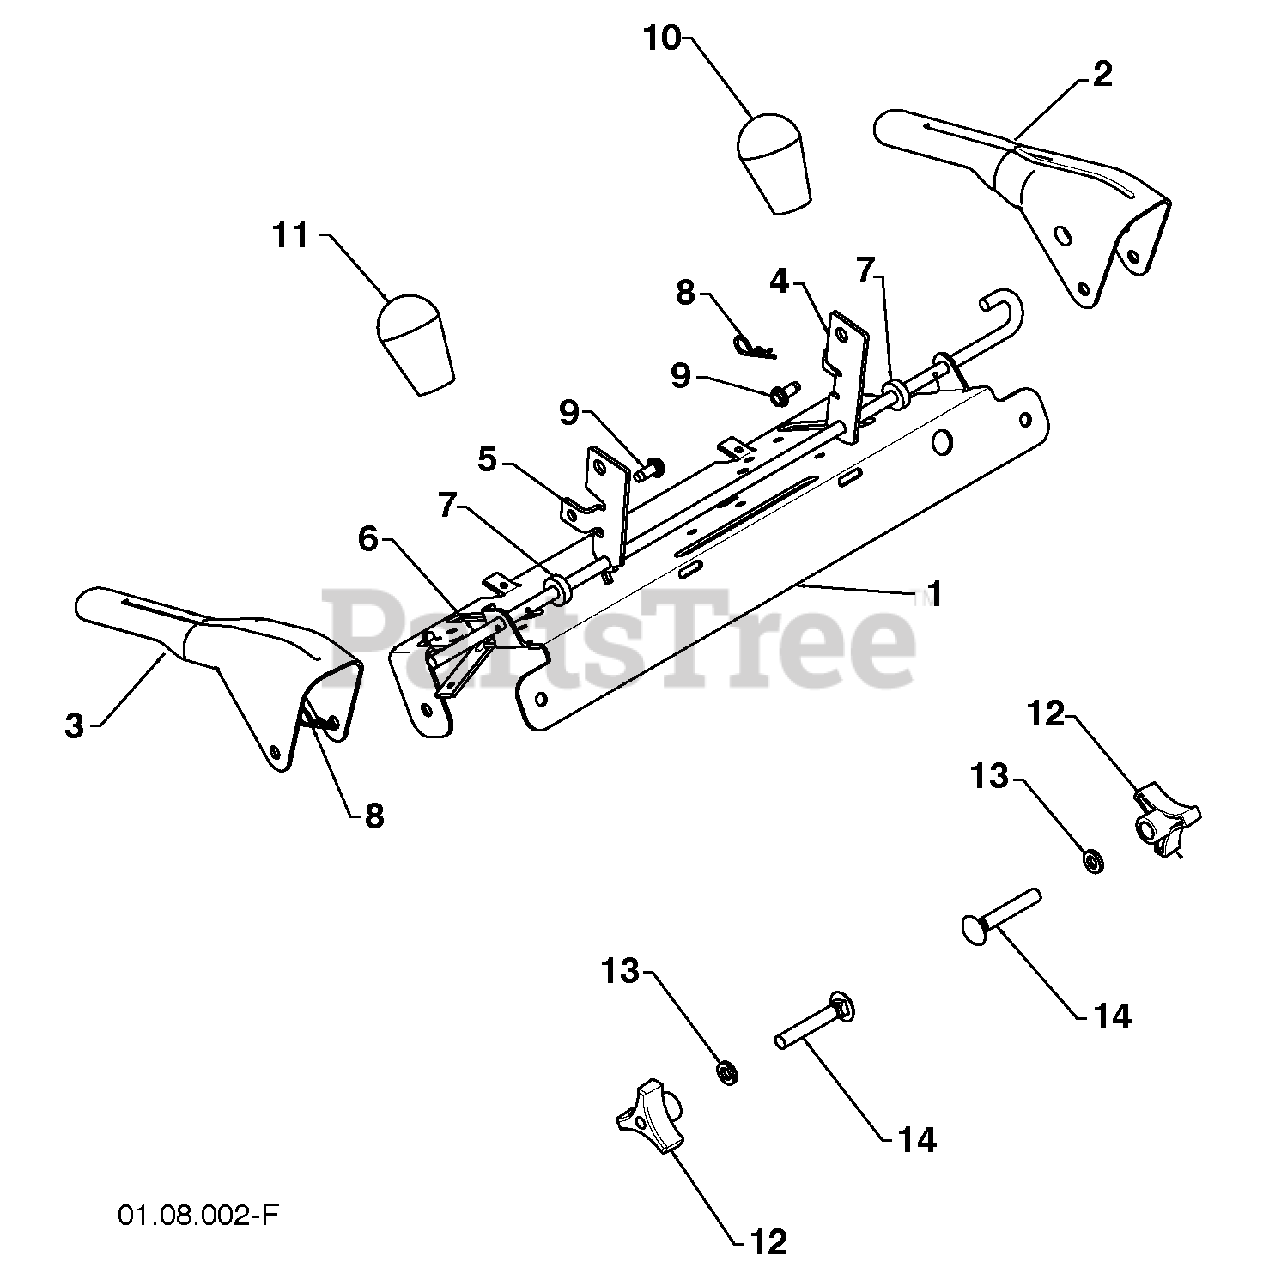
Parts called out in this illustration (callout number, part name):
2	CONTROL LEVER LH
3	CONTROL LEVER RH
4	TRACTION ROD ARM
5	IMPELLER ROD ARM
6	INTERLOCK BAIL
8	RETAINER
9	SCREW 1/4-20 X .62
10	KNOB BLACK
11	KNOB RED
12	HANDLE KNOB
13	WASHER 3/8
14	CARRIAGE BOLT 3/8-16 X 2.25
